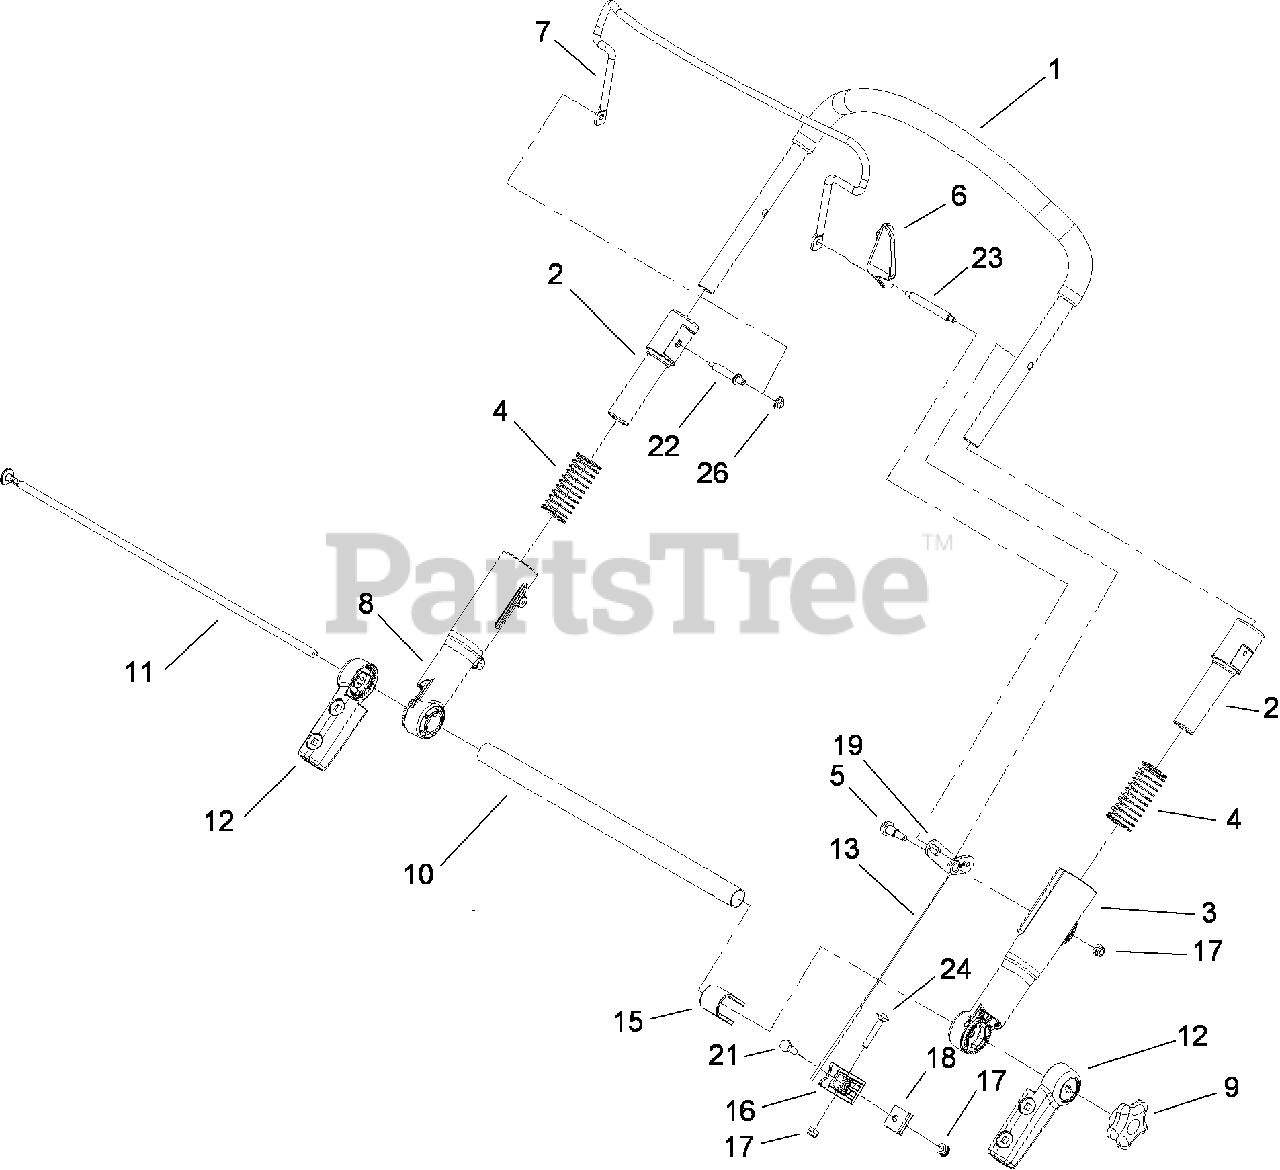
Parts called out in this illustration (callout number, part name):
1	UPPER HANDLE ASM
2	SLEEVE-INNER
3	SLEEVE-OUTER, LH
4	SPRING-COMPRESSION
5	BOLT-SHOULDER
6	STOP-PIVOT
7	BAIL-BRAKE
8	SLEEVE-OUTER, RH
11	ROD-THREADED
12	MOUNT-HANDLE, LOWER
13	CABLE-TRACTION
15	SUPPORT-CABLE
16	SUPPORT-GUIDE, CABLE
17	NUT-LOCK, NI
18	CLAMP-CABLE
19	LEVER-TRACTION
21	SCREW-HH
22	PIN-HANDLE
23	PIN-BAIL, LH
24	SCREW-CARR
26	RETAINER-PUSH ON
